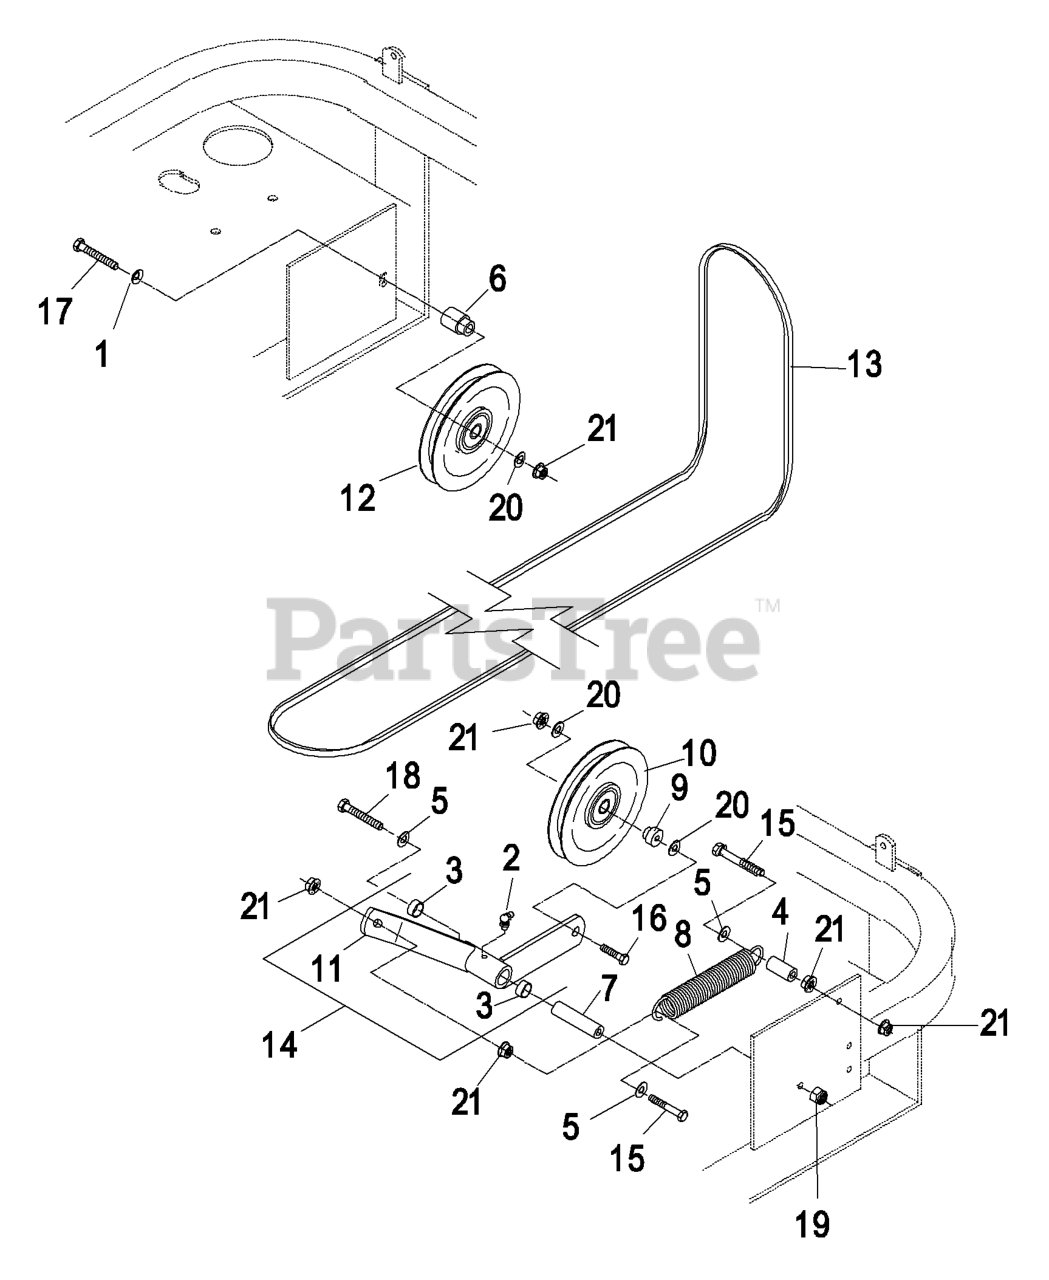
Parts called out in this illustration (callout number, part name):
1	WASHER-BELLEVILLE
2	FITTING-GREASE, 90 DEG
3	SLEEVE-BEARING
5	WASHER-FLAT
6	BUSHING-IDLER
7	BUSHING-PIVOT, IDLER
8	SPRING-EXTENSION
9	BUSHING-IDLER
10	PULLEY-IDLER
12	PULLEY-IDLER
13	KIT,MULE DRIVE BELT
14	ARM ASM
15	SCREW-HH
16	SCREW-HH
17	SCREW-HH
18	SCREW-HH
19	NUT-LOCK, NI
20	WASHER-FLAT
21	NUT-HHF, WHIZ
